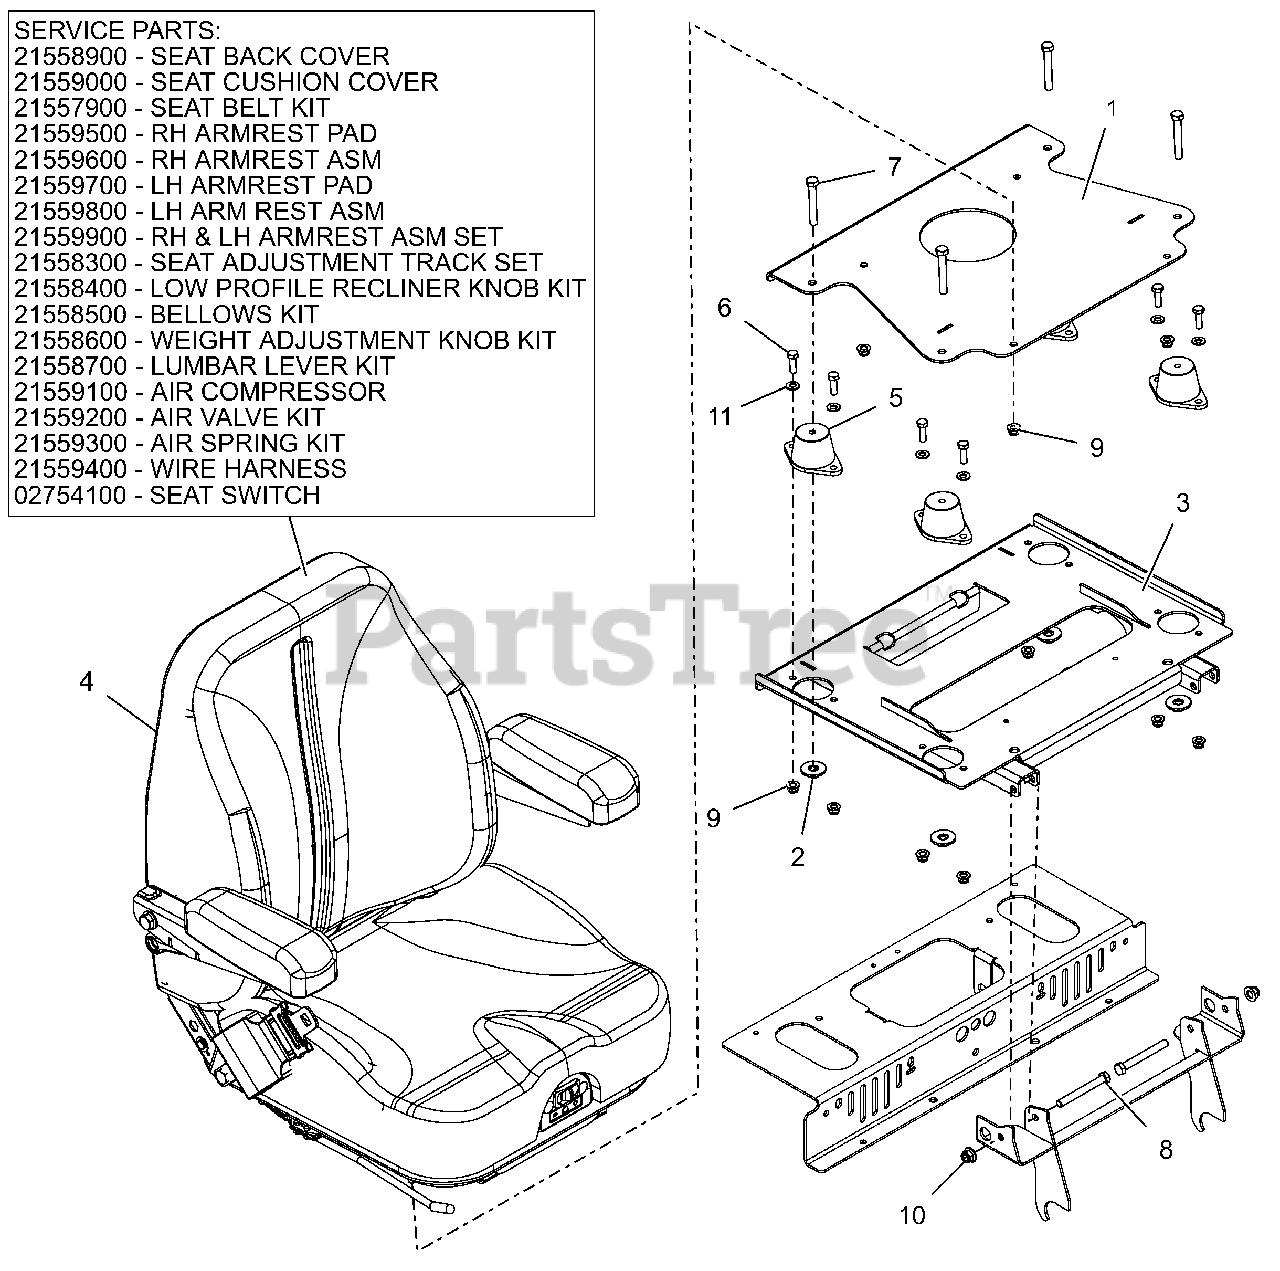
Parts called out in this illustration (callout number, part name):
1	WMT, SEAT PLATE
2	WLDMT, SEAT RETAINER
3	SEAT ISO MTG WMT W/SFTY DECAL
4	SEAT, AIR SUSPENSION
4	COVER, SEAT BACK
4	COVER, SEAT CUSHION
4	KIT, SEAT BELT
4	PAD, RH ARMREST
4	ASM, RH ARMREST
4	PAD, LH ARMREST
4	ASM LH ARMREST
4	SET, RH & LH ARMREST ASM
4	SET, SEAT ADJUSTMENT TRACK
4	KIT, LOW PROFILE RECLINER KNOB
4	KIT, BELLOWS
4	KIT, WEIGHT ADJUSTMENT KNOB
4	KIT, LUMBAR LEVER
4	COMPRESSOR, AIR RIDE SEAT
4	KIT, AIR VALVE AND LINE
4	KIT, AIR SPRING
4	HARNESS, SEAT WIRE
4	SWITCH- SNAP MTG N.O.
5	MOUNT, ISOLATOR
6	@BLT-HEX .31-18X1.00 GR5 YWZC
7	BLT-HEX .38-16X2.50 FTH YWZC
8	@BLT-HEX .38-16X3.25 GR5 YWZC
9	@NUT-LK-NYL-FLG .31-18 YWZC
10	@NUT-LK-NYL-FLG .38-16 YWZC
11	@WSHR-FL-STL.344X.688X.065YWZC
